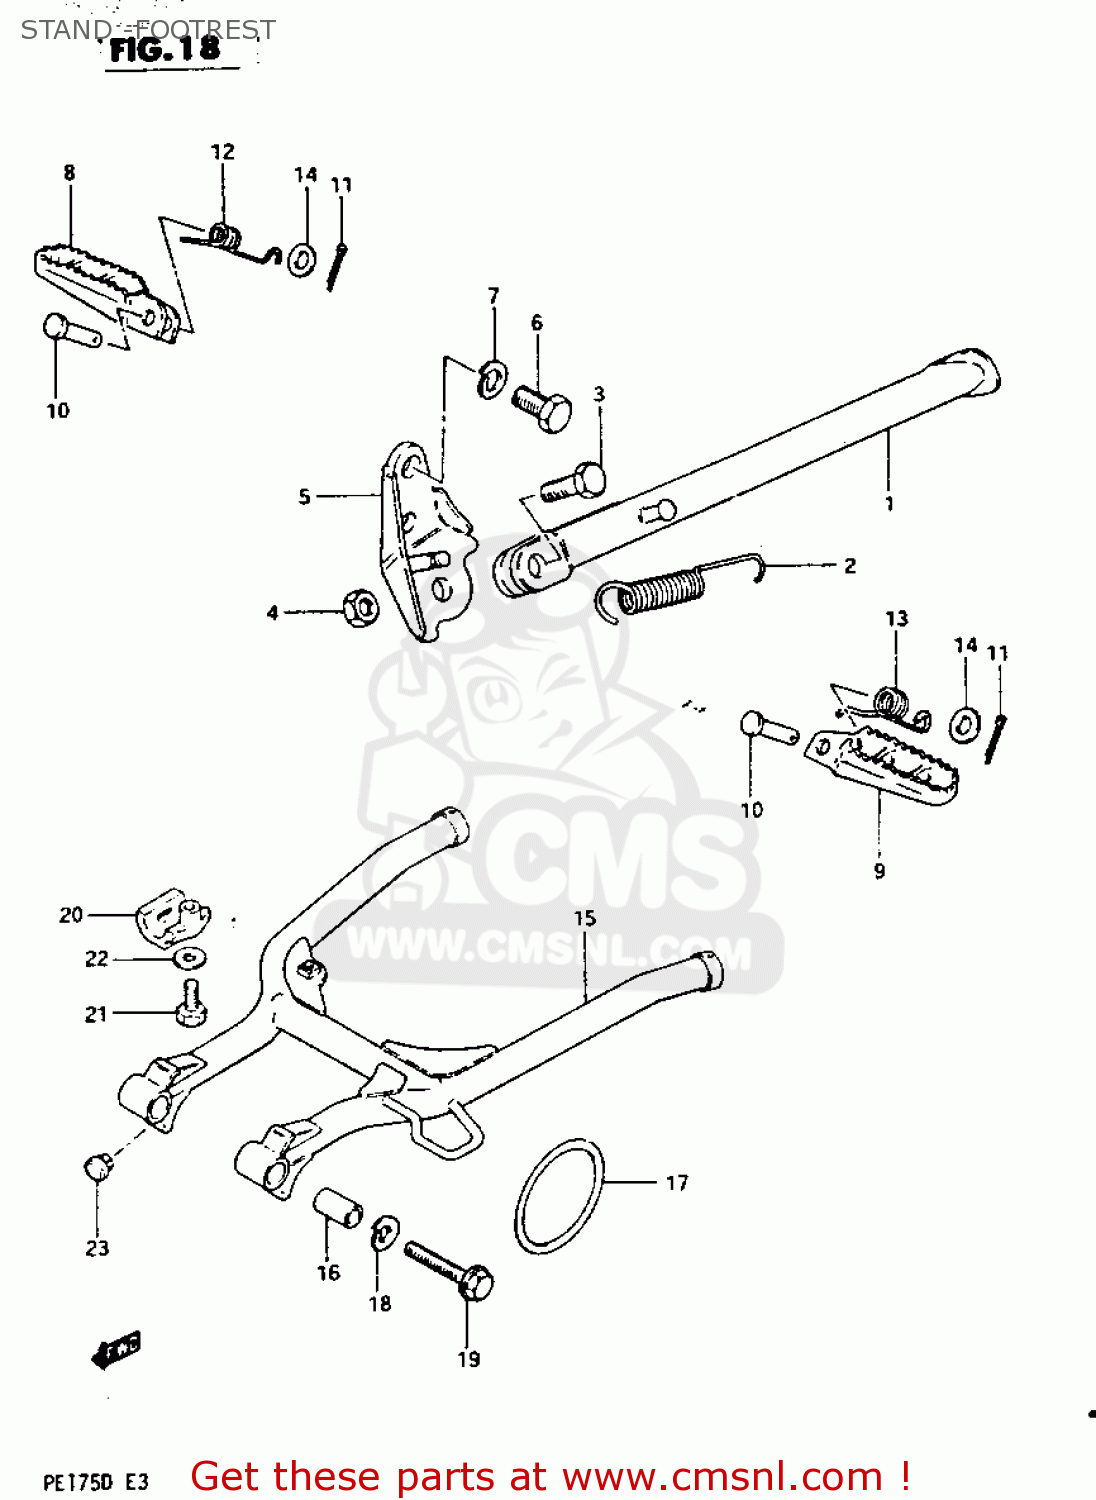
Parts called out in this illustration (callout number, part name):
1	STAND,PROP
2	SPRING
3	BOLT(10X30)
4	NUT
5	BRACKET,SIDE STAND
6	BOLT(10X19)
7	WASHER,LOCK,10
8	FOOTREST,FR,R
9	FOOTREST,FR,L
10	PIN
11	PIN 20X20
12	SPRING
13	SPRING
14	WASHER
15	STAND,CENTER
16	SPACER(10.5X16X30)
17	O RING CTR STAND
18	WASHER,LOCK,10
19	BOLT, RH
20	PROTECTOR CTR STAND
21	BOLT
22	WASHER
23	CUSHION
